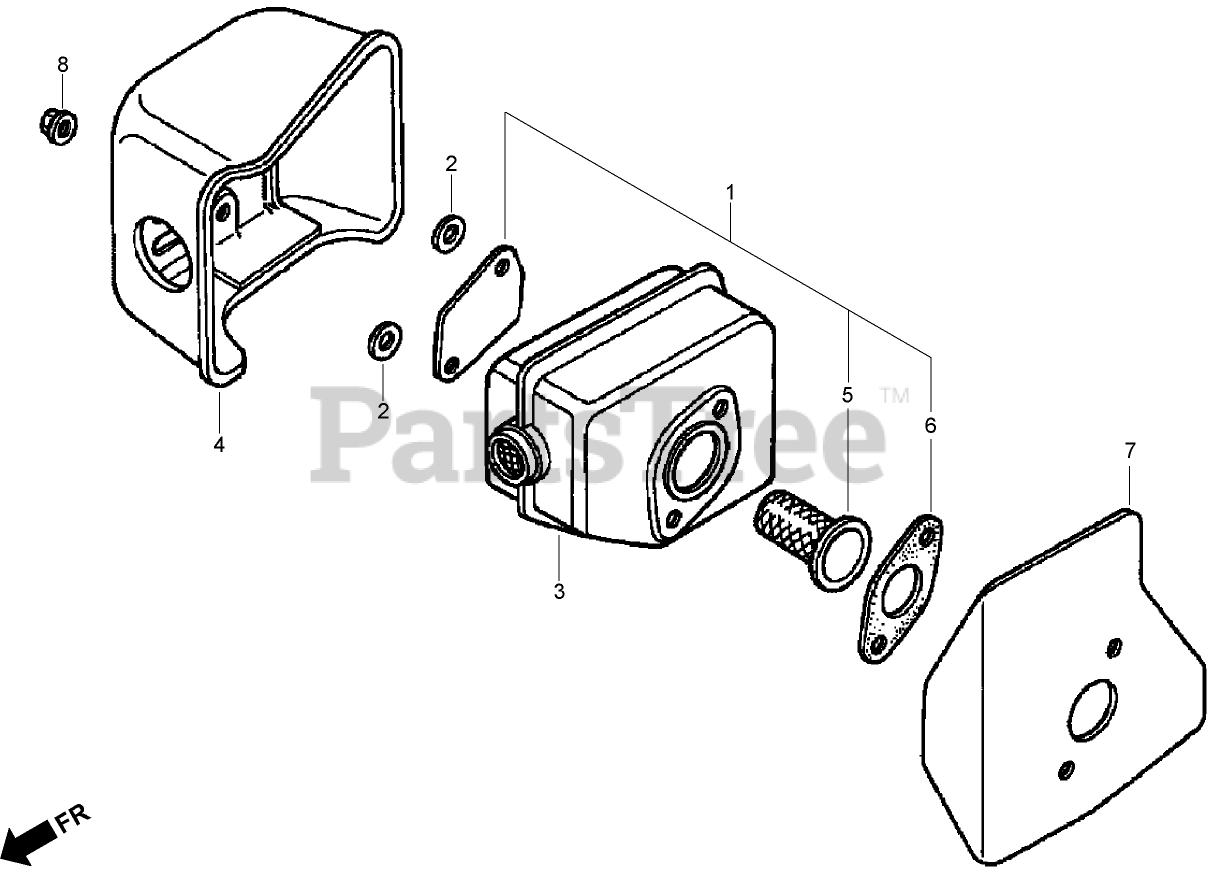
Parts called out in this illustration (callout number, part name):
1	SPARK ARRESTER KIT
2	GASKET-PROTECTOR
3	MUFFLER
4	PROTECTOR-MUFFLER
5	SPARK ARRESTER KIT
6	Gasket-Muffler
7	GASKET-MUFFLER
8	NUT-LOCK, SELF (6 mm)
